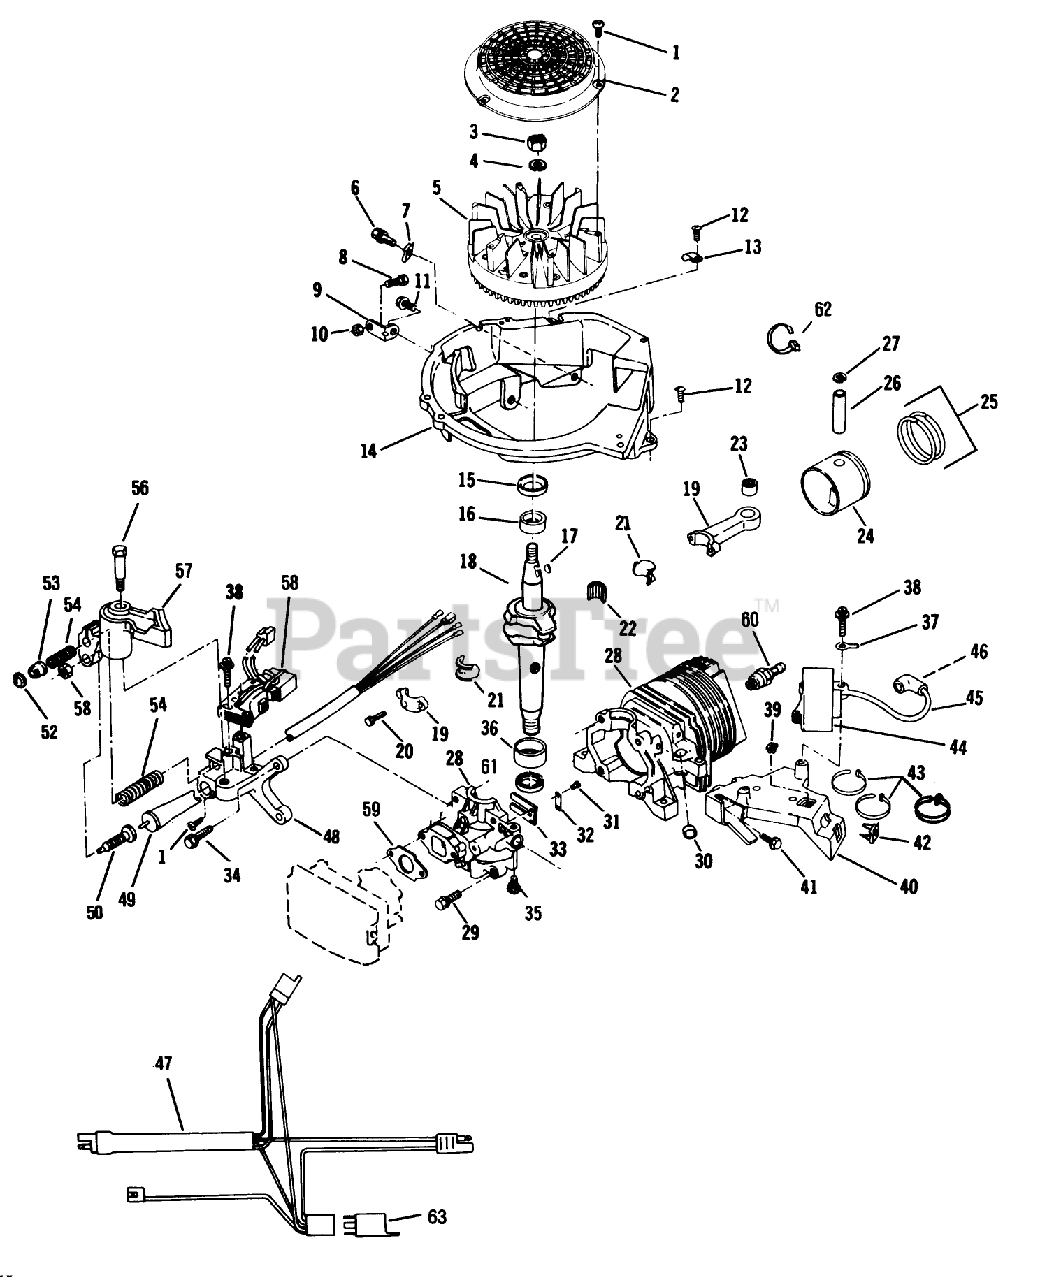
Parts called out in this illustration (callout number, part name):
1	SCREW F
3	NUT
5	FLYWHEEL ASSY F
6	SCREW-SEMS
8	BOLT F
10	NUT-LOCK F
12	SCREW F
14	BASE SHROUD F
16	BEARING V
17	KEY
20	SCREW-HSH
21	LINER ASM
23	BEARING AY F
27	RING-RETAINING
29	SCREW S
30	PLUG-CORE VF
32	PLATE-BACKUP, REED
36	BEARING V
37	TERMINAL S
39	NUT-CLIP
40	BRACKET S
42	NUT-CLIP
45	HT LEAD&COVER XEV
48	BRACKET F
50	PLUNGER S
51	SPRING-BRAKE
52	RETAINER S
53	ACTUATOR-LEVER, BRAKE
54	SPRING
59	GASKET CARB S
61	SEAL-OIL
